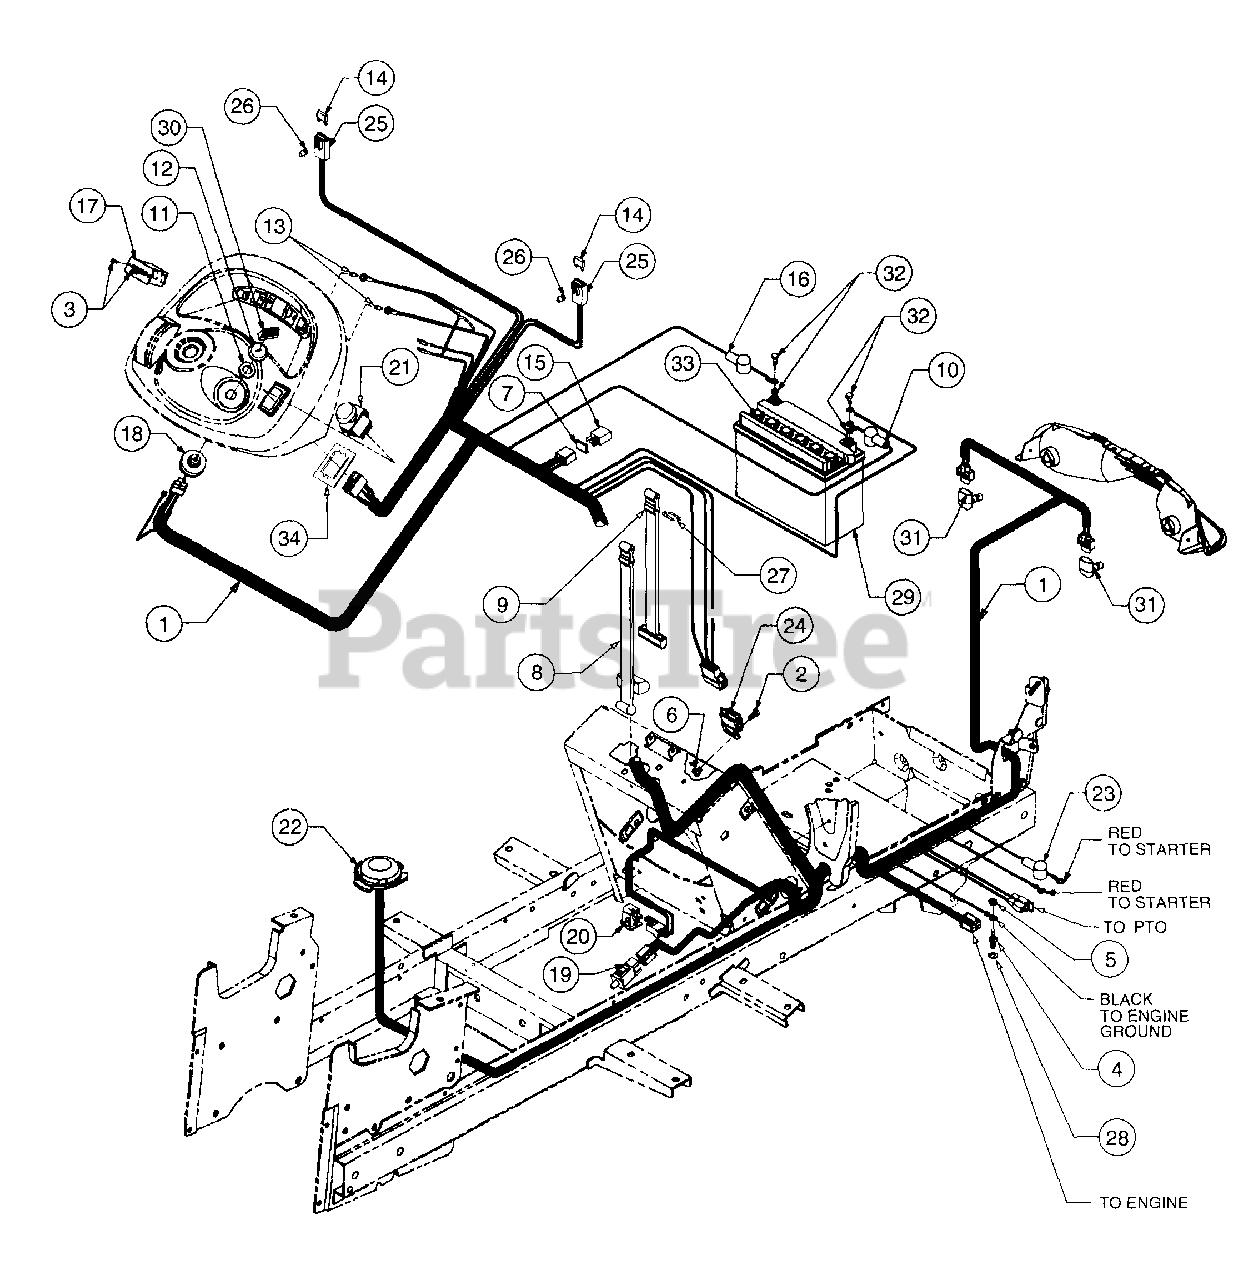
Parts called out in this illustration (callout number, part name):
1	Wire Harness, Main
2	Screw, Hex Cap, 1/4-20 x .625 GR5
3	Screw, Truss Hd Tapp, #6 x .62
4	Stud, Ground
5	Nut, Hex, 5/16-18
6	Nut, Hex Sems, 1/4-20
7	Gasket, Silicone
8	Strap, Battery Retainer
9	Strap, Battery Retainer
10	Cover, Terminal Black
11	Nut, Ignition Switch
12	Cap, Ignition Switch
13	Bulb, Indicator
14	Fuse, 20 Amp
15	Relay
16	Cover, Terminal Red
17	Hour Meter
18	Switch, Ignition
19	Switch, Interlock (Brake)
20	Switch, Snap Mount - Normally Closed
21	Switch, PTO
22	Switch, Seat
23	Cover, Terminal Red
24	Module, Voltage Sensor
25	Holder, Fuse
26	Clip, Fuse Holder Mounting
27	Hook, Wire Rectangular
28	Washer, External Lock, 5/16
29	Battery
30	Key, Ignition
31	Bulb, Head Lamp
32	Battery Cable Hardware
33	Cap, Battery
34	Bracket, PTO Switch Retainer
